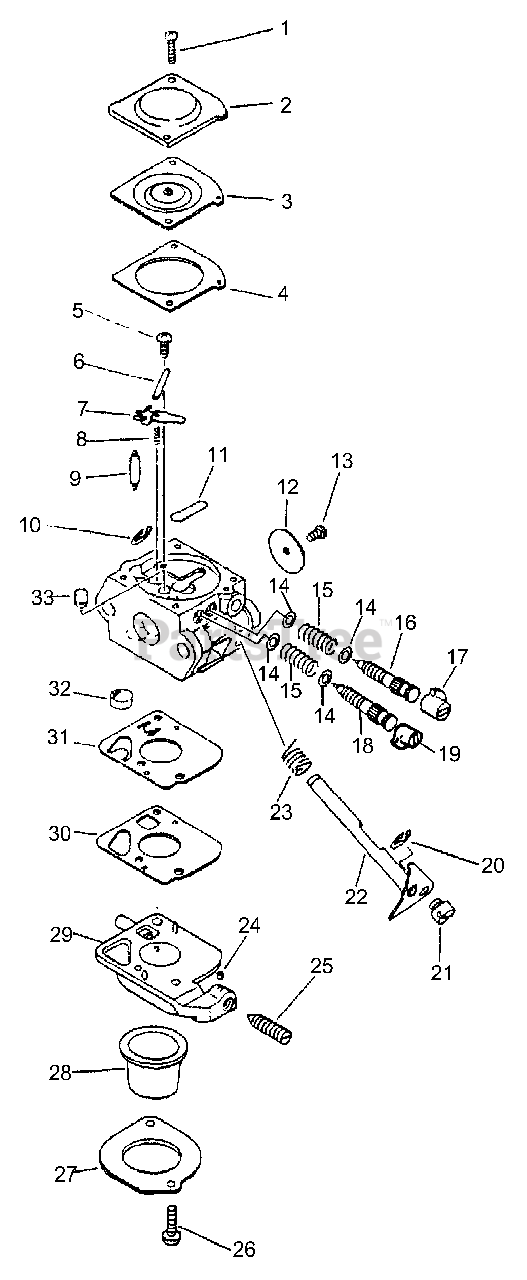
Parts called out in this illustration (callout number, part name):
2	COVER, METERING
3	DIAPHRAGM, METERING
4	GASKET, METERING
5	SCREW, METERING LEVER PIN
6	PIN, METERING LEVER
7	LEVER, METERING
8	SPRING, METERING LEVER
9	VALVE, NEEDLE
10	RING, RETAINING
11	PLUG, WELCH
12	VALVE, THROTTLE
16	NEEDLE - LOW SPEED
17	CAP, LIMITER
18	NEEDLE - HIGH SPEED
19	CAP, LIMITER
20	RING, RETAINING
22	SHAFT, THROTTLE
23	SPRING, RETURN
24	PIECE, FRICTION
25	SCREW, IDLE ADJUST
26	SCREW, RETAINER
27	RETAINER, PURGE BULB
28	BULB, PURGE
29	BASE, PURGE
30	GASKET, PUMP
31	DIAPHRAGM, PUMP
32	STRAINER
33	NOZZLE, CHECK VALVE
33	REPAIR KIT
33	DIAPHRAGM/GASKET KIT
